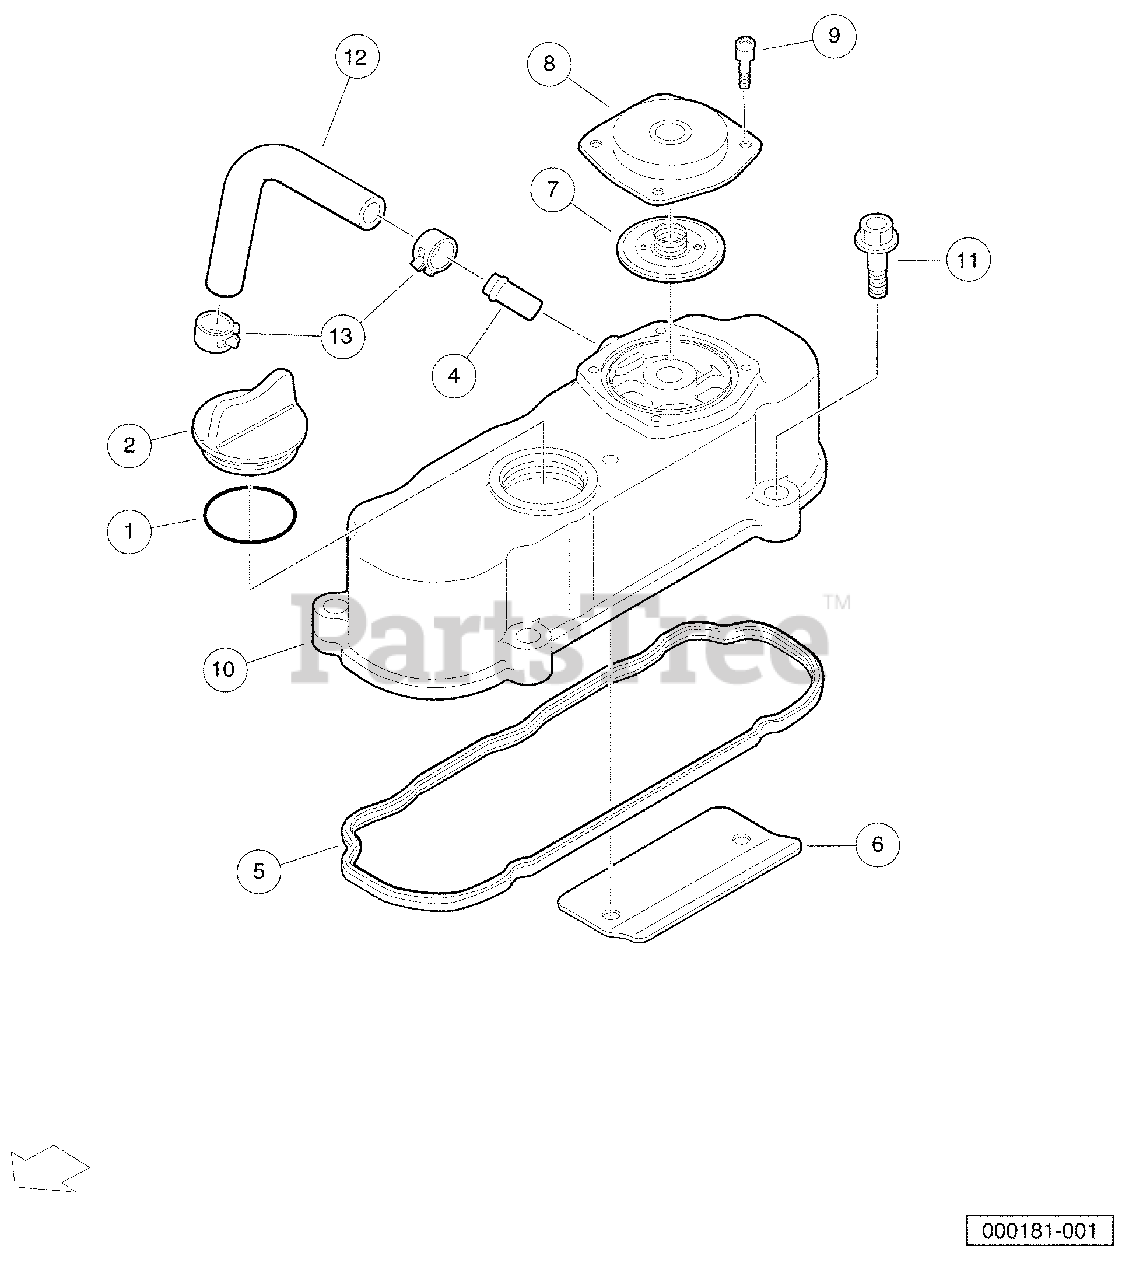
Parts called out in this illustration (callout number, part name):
1	O Ring, 30 X 36
2	Plug, Oil Filler.
3	Assembly, Cylinder Head Cover
4	Pipe, Water Return, D722
5	Gasket, Cylinder Head Cover.
6	Shield, Breather.
7	Valve, Breather
8	Cover, Breather
9	Screw, Breather.
10	Cover, Cylinder Head
11	Bolt, Cylinder Head Cover
12	Tube, Breather.
13	Clamp, Breather Tube
